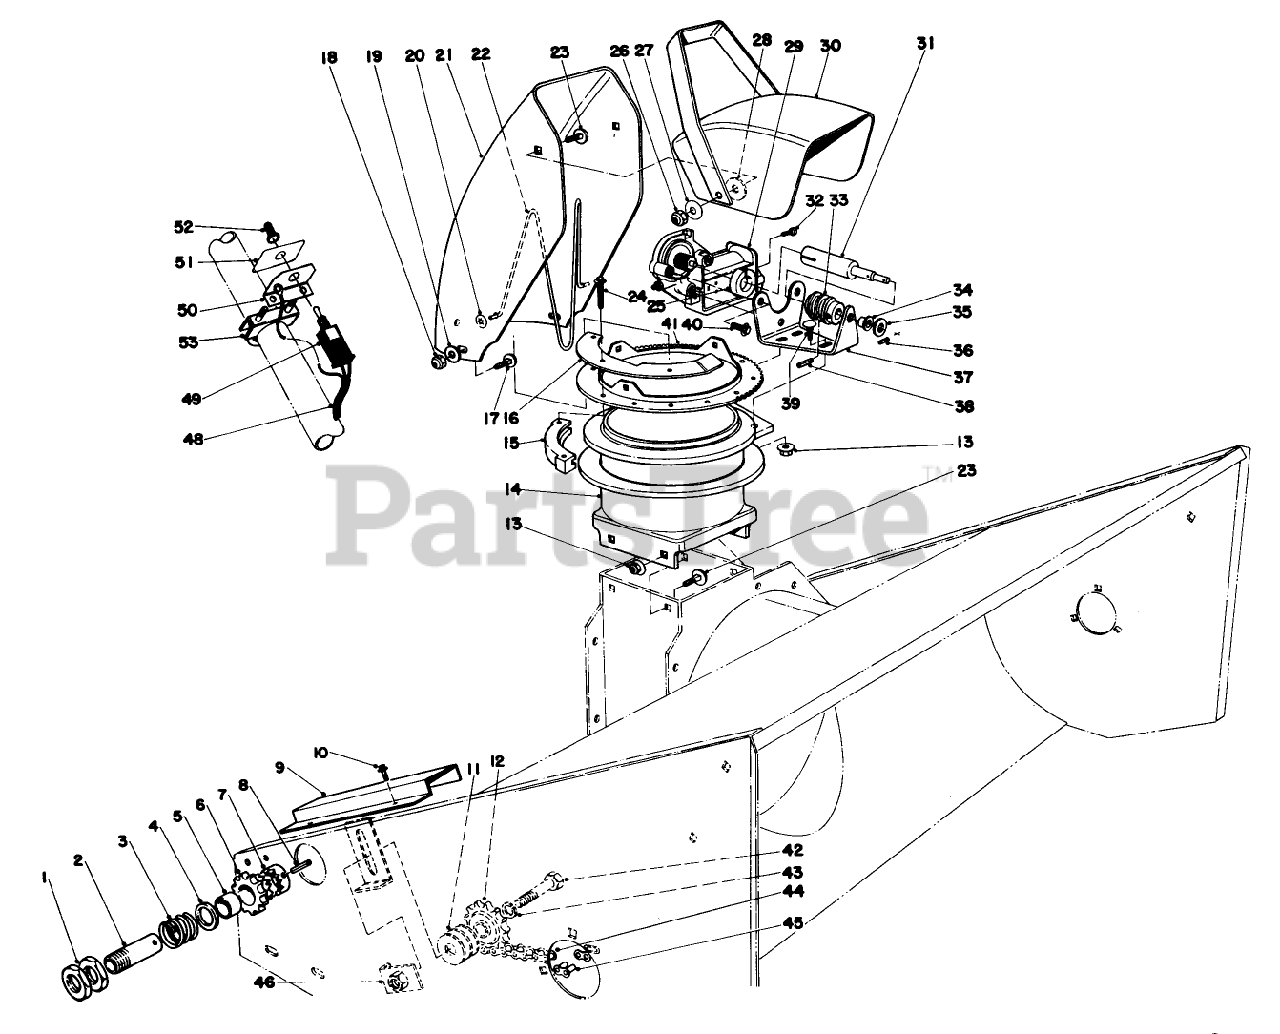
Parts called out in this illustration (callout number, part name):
1	Nut-Thin
2	Clutch Sleeve
3	Spring Compression
6	Clutch Sprocket
7	Clutch Collar
8	PIN-ROLL
9	Chain Cover
10	SCREW-HWHTF
11	WASHER-FLAT
12	IDLER SPRKT (60016)
13	NUT-HHF, WHIZ
14	Chute Transition
15	RETAINER-CHUTE
16	Stop-Chute Rotator
17	SCREW-CARR
18	NUT-LOCK, NI
19	WASHER-PLAIN
20	NUT-PUSH
21	Upper Chute
22	WIRE-CHUTE
23	SCREW-CARR
24	SCREW-SPECIAL
25	SPLIT COLLAR
26	NUT-LOCK, CONE
27	WASHER-BELLEVILLE
28	WASHER-RUBBER
29	ELEC GEAR MOTOR
30	Deflector
31	WORM GEAR SHAFT
32	SCREW-HSH
33	GEAR-WORM, CHUTE
34	FLANGE BSHG #FF-310-3
35	WASHER-FLAT
36	3/32 X 9/16 ROLL PIN
37	Motor Mount
38	PIN-SPRING
39	BOLT-CARR
40	SCREW-HHF
41	RING - CHUTE SWIVEL
42	SCREW-HH
43	WASHER-LOCK
44	ROLLER CHAIN (60023)
45	LINK-CHAIN
46	NUT PLATE WA (60095)
48	WIRE HARNESS
49	Toggle Switch Assembly (Incl. Ref. #50)
50	Toggle Switch Mount
51	DECAL
52	BOOT-SWITCH
53	CLAMP
